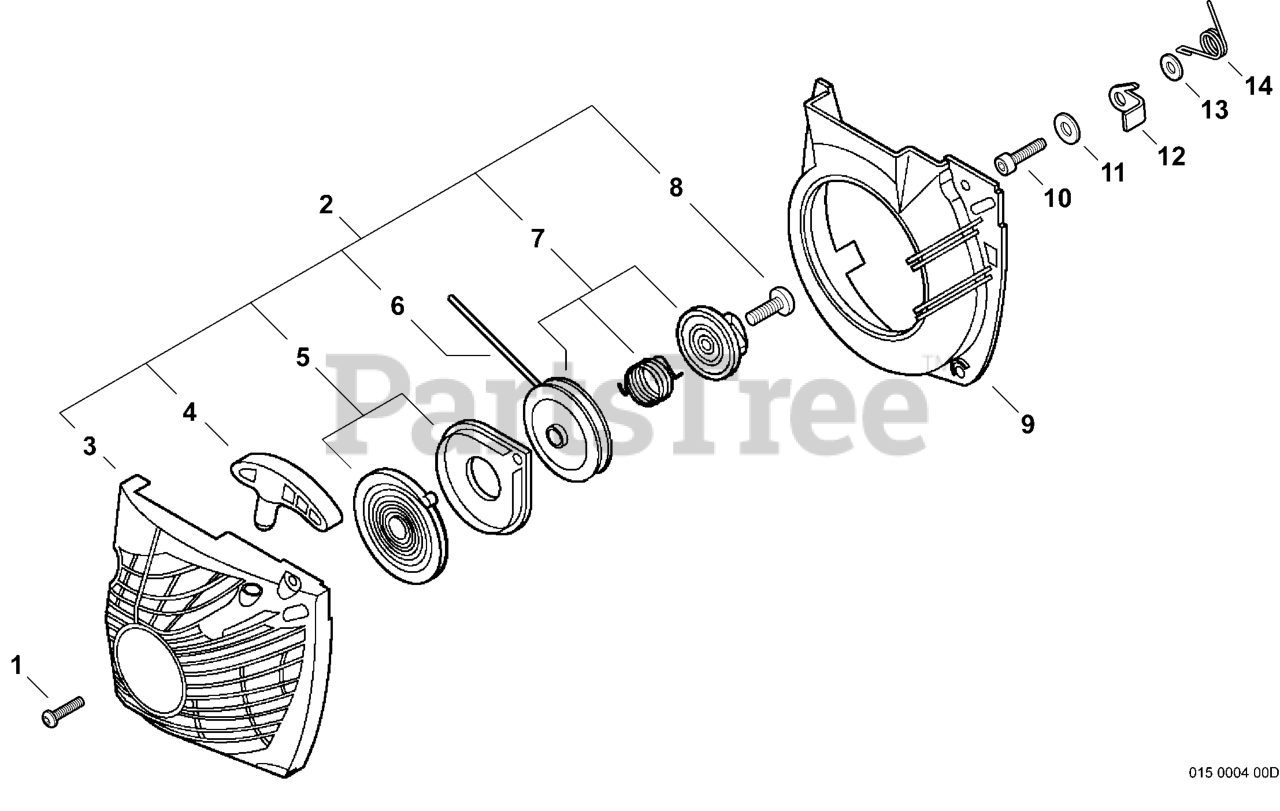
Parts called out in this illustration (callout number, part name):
1	SCREW, TAPPING 5x20
2	STARTER ASSY, RECOIL - I-START
3	CASE, RECOIL STARTER
4	GRIP, STARTER
5	SPRING SET, RECOIL
6	ROPE, STARTER 3.5x900
7	REEL KIT, ROPE
8	SCREW
9	COVER, FAN
10	BOLT 5x14
11	WASHER 5.5x12x0.8
13	SPACER 5.2x8x2.1
14	SPRING, TORSION
